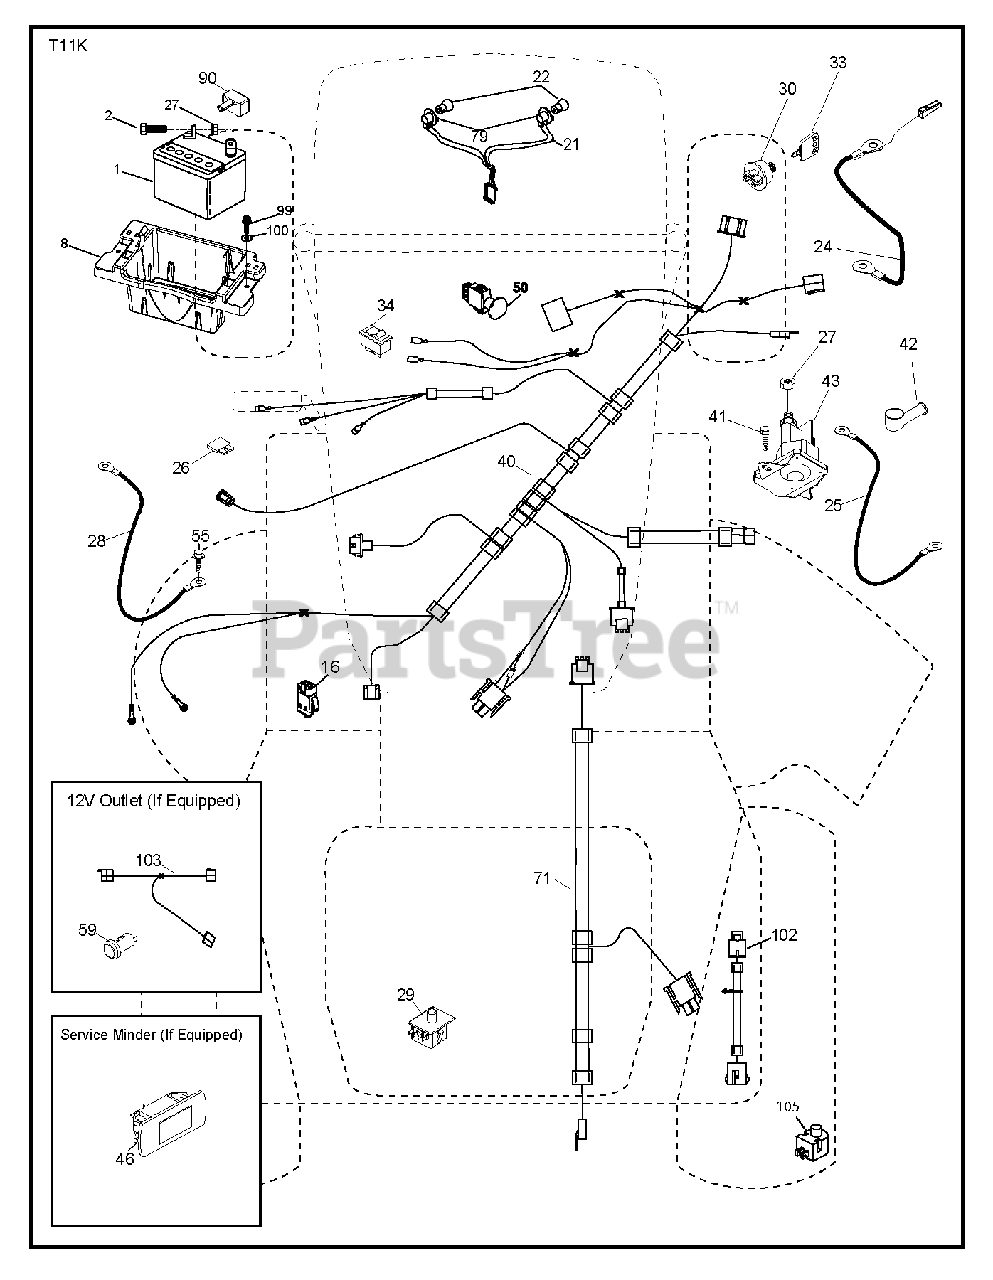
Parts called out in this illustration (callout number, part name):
1	Battery, Dry 30 Amp
2	BOLT.HEX.1/4.X.3/4.DICHROMATE
8	TRAY.BATTERY BOX.FRONT
16	SWITCH INTERLOOK PUSH-IN
21	HARNESS.LIGHT W/4152J BULBS
24	CABLE.FRBATT.W/WIRE.8GA.8
25	CABLE.STARTER.8GA.17.5
26	FUSE 20AMP
27	NUT
28	CABLE.GROUND.21"BLK.8GA.90T
29	SWITCH.SEAT.DP W/RAMPS
30	SWITCH.IGN.DELTA.W.LGH.ROS
33	KEY.CHAIN.BLISTER.PACK.GEN.USA
40	HARNESS HARNESS..DASH.ING.ELEC
41	SCREW
42	TERMINAL COVER
43	SOLENOID.STARTER.BRASS.PLUNGER
46	GUAGE.SRVCMNDR.HRMTR.
50	SWITCH.PTO.8TERMINAL.STD.BLK
55	SCREW 5/16"
71	HARNESS-CHASSIS SUB
79	BULB HOLDER ASM.
90	COVER.TERMINAL.BATTERY
99	SCREW HEXWSHR 1/4-20X3/4
102	HARNESS PIGTAIL PCH TEX ROS
105	REVERSE SWITCH
